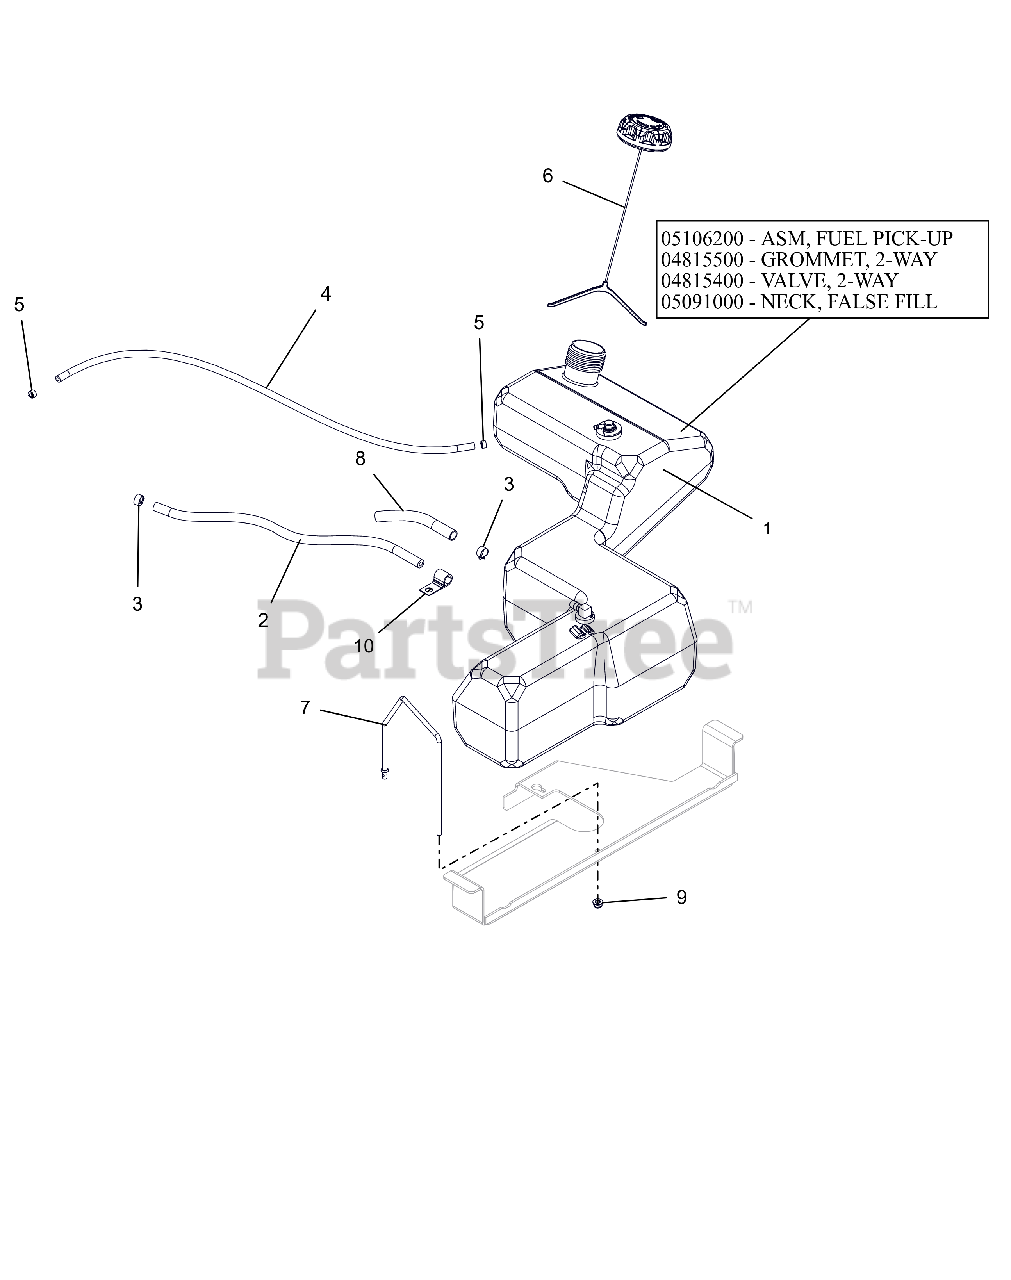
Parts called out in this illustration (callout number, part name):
1	ASSY, FUEL TANK-IKON
1	ASM, IKON FUEL PICK-UP
1	GROMMET, 2-WAY
1	VALVE, 2-WAY
1	NECK, FALSE FILL-2017 IKON
2	HOSE, .25 LOW-PERM BULK GAS
3	CLAMP, FUEL LINE
4	HOSE, .188 LOW-PERM BULK GAS
5	CLAMP-HOSE, SPRING .188
6	CAP, FUEL VENT-IN 2.25" RATCH.
7	BRKT, FUEL TANK HOLD DOWN
8	WRAP, ANTIABRASION .5X.064WALL
9	@NUT-LK-NYL-FLG .25-20 YWZC
10	J-CLAMP
